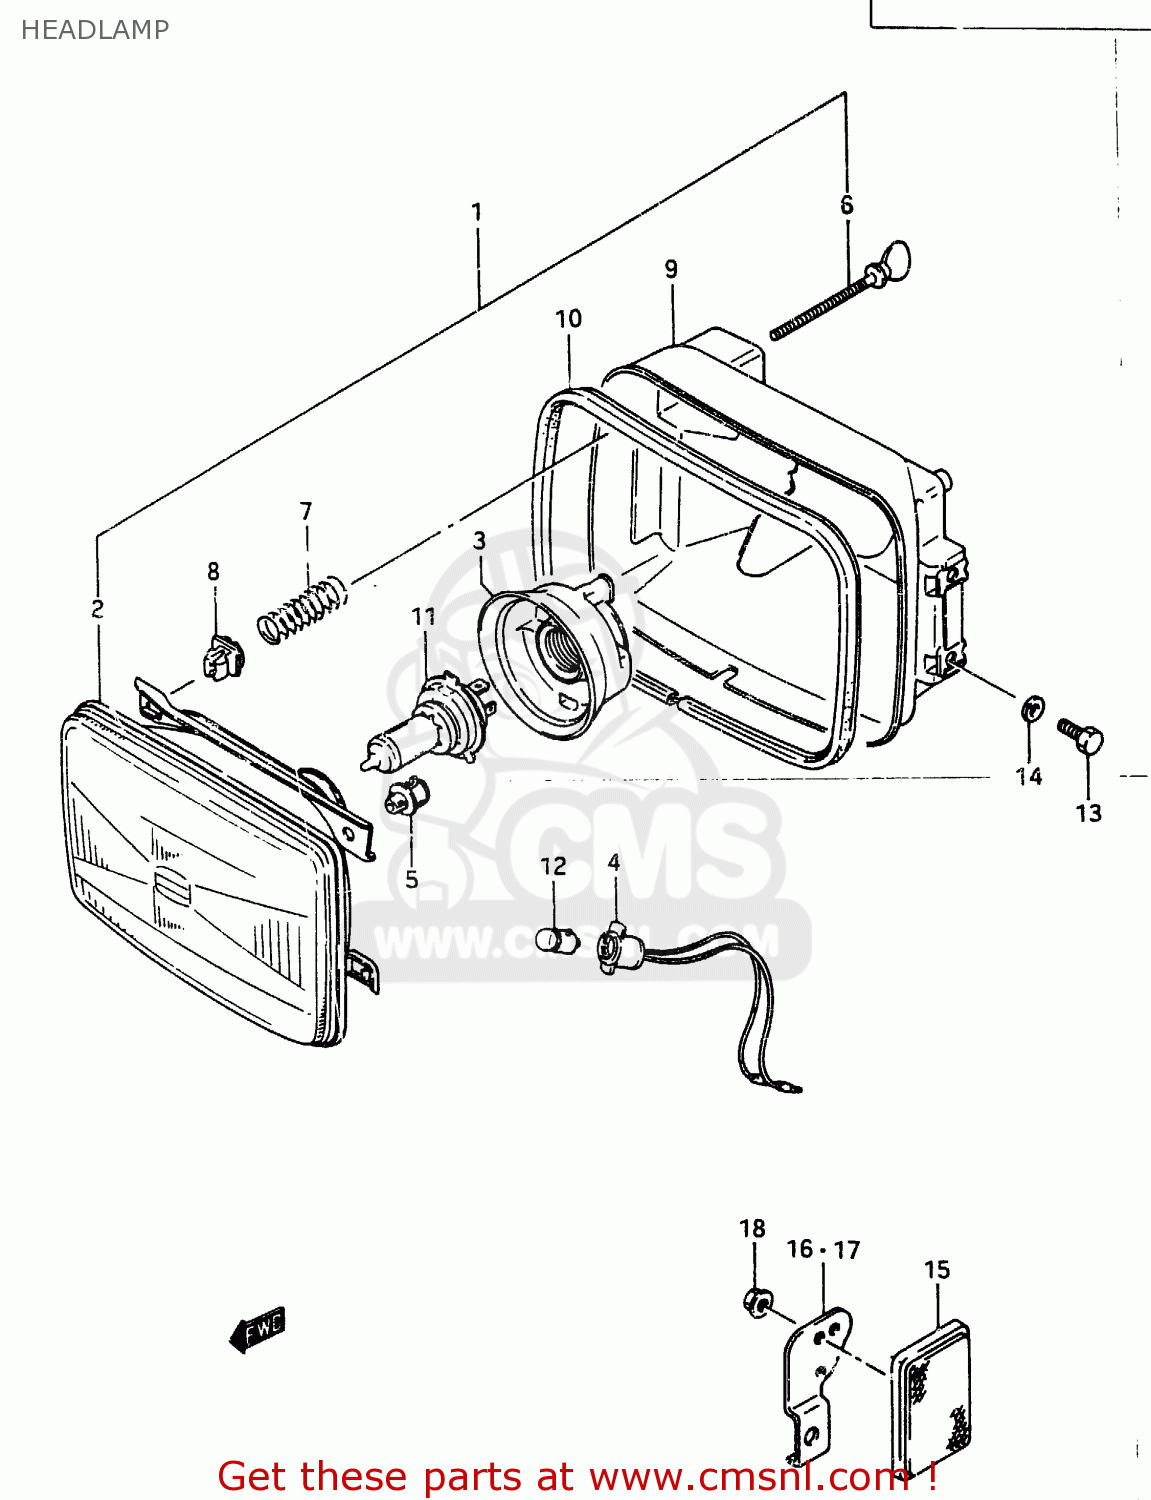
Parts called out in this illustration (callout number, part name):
1	HEADLAMP ASSY
2	UNIT
3	COVER,SOCKET
4	SOCKET
5	SCREW,SPHERICAL
6	SCREW,ADJUSTER
7	SPRING
8	NUT
9	HOUSING
10	GASKET (NAS)
11	BULB(12V60/55W,H4)
12	BULB(12V4W)
13	BOLT
14	WASHER,LOCK
15	REFLEX REFLECTOR, REAR SIDE
16	BRACKET, RH
17	BRACKET, LH
18	NUT
